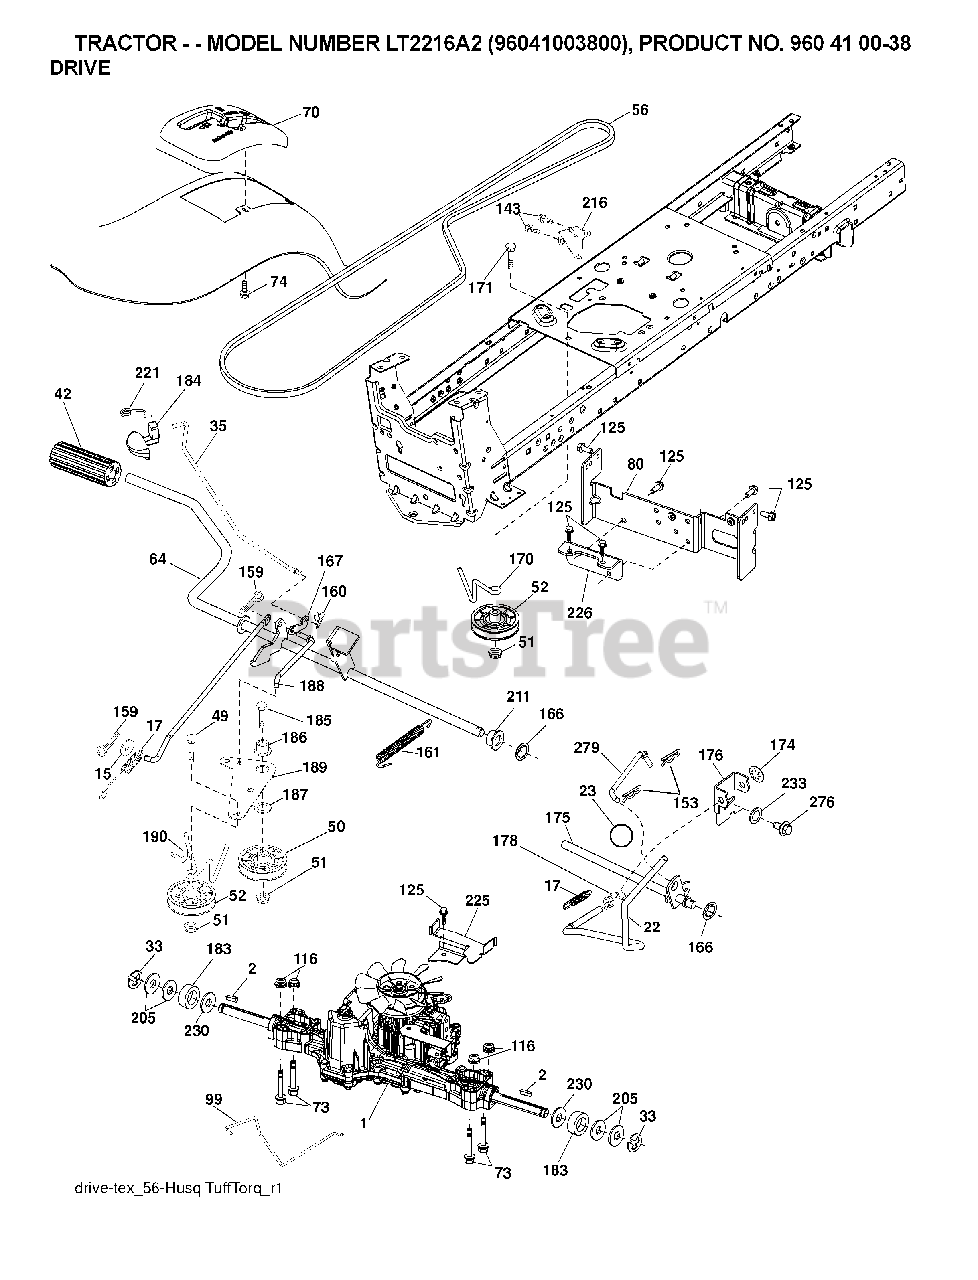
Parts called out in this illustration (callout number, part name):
1	TRANSAXLE.K46A
2	SQUARE KEY
17	SPRING.BRAKE.K46.GREEN
22	ROD.SHIFT.FENDER.TLT.2006
23	PISTOL KNOB
29	ROD.BRAKE.K46
33	E-RING LT
35	FUEL CAP
42	PEDAL COVER T
49	BOLT
50	IDLER.FLAT.910.OFFSET
51	NUT LOCK FLG 3/8-16 UNC
52	IDLER.V-GROOVE.910.OFFSET
64	SHAFT.ASM.PEDAL.BRAKE.
70	CONSOLE.SHIFT.STL.HYD.BLACK
73	BOLT HEX 5/16-18 GR 5
74	SCREW.HI-LO.CONSOLE
80	STRAP.TORQUE.HG3000/K46
99	ROD ASM BYPASS
116	NUT LOCK HEX FLANGE 5/16-18
125	SCREW
143	SCREW LT
153	RETAINER M
159	COTTER PIN
160	RETAINER CLIP
161	SPRING.RETURN.CLUTCH.2006
162	SPACER.TRANSAXLE.18&22
165	BUSHING.SHAFT.BRAKE.HAND
166	NUT.PUSH.625.2006
167	LATCH.BRAKE.SPRING
170	KEEPER.V-IDLER.CENTER.
171	BOLT
174	NUT.PUSH.500.2006
175	SHAFT ASM SHIFT
176	ARM.CLEVIS.ROD.SHIFT
178	SPRING.SHIFT.GT2006
183	SPACER AXLE
184	HANDLE.PAKRING.BRAKE.
185	BOLT
186	SPACER.RETAINER
187	WASHER 12/32X2X10GA
188	LINK.CLUTCH.GROUND.DRIVE
189	BELLCRANK.GROUND.DRIVE.TEX.
190	KEEPER.BELLCRANK.DRIVE
195	BRKT.ROD.BRAKE.PEERLES
211	BUSHING.SHAFT.BRAKE.HAND
216	BRACKET.PULLEY.IDLER.W/TEX
221	RETAINER.SPRING.CLIP.H
225	KEEPER.BELT.TRANSAXLE.K46
226	BRACKET.MOUNT.TORQUE.K46.TLT
230	WASHER.HARDENED
233	WASHER SERRATED
276	BOLT FIN HEX 7/16-14 X 1
279	LINK SHIFT
